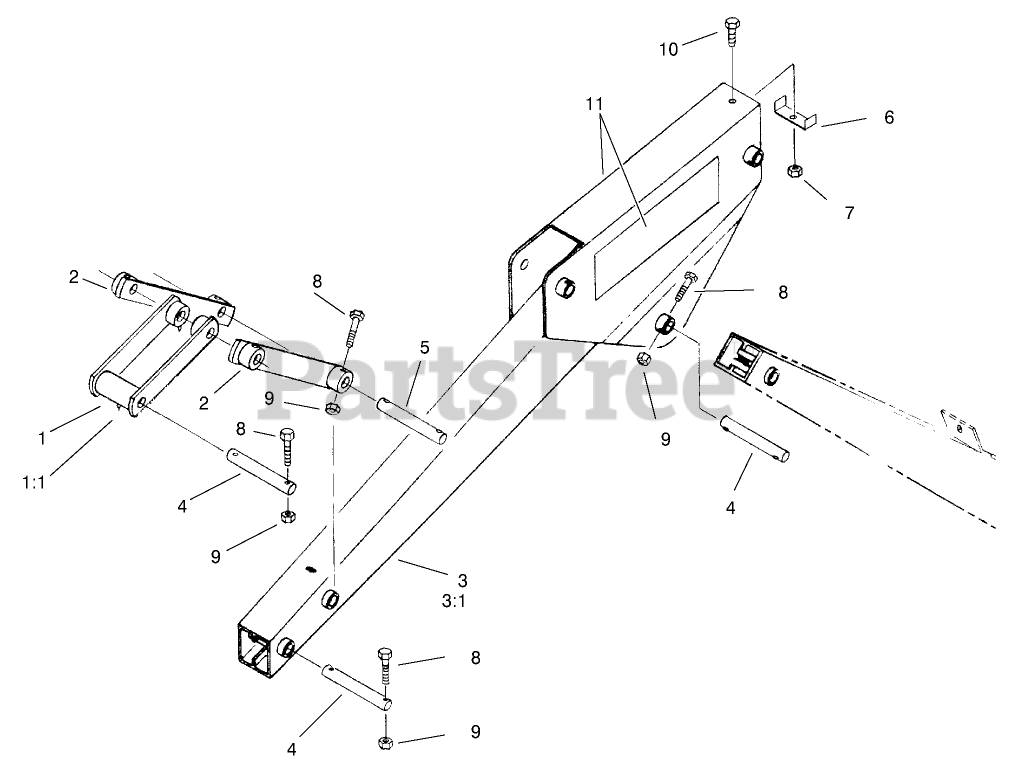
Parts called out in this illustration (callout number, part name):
1	LINKAGE ASM
1:1	FITTING-GREASE
2	LINKAGE STRAP ASM
3	CROWD ARM ASM
3:1	FITTING-GREASE
4	PIN-BUCKET
5	PIN-LINKAGE
6	BRACKET-HOSE
7	NUT-LOCK, NI
8	SCREW-HH
9	NUT-LOCK
10	SCREW-HH
11	DECAL
